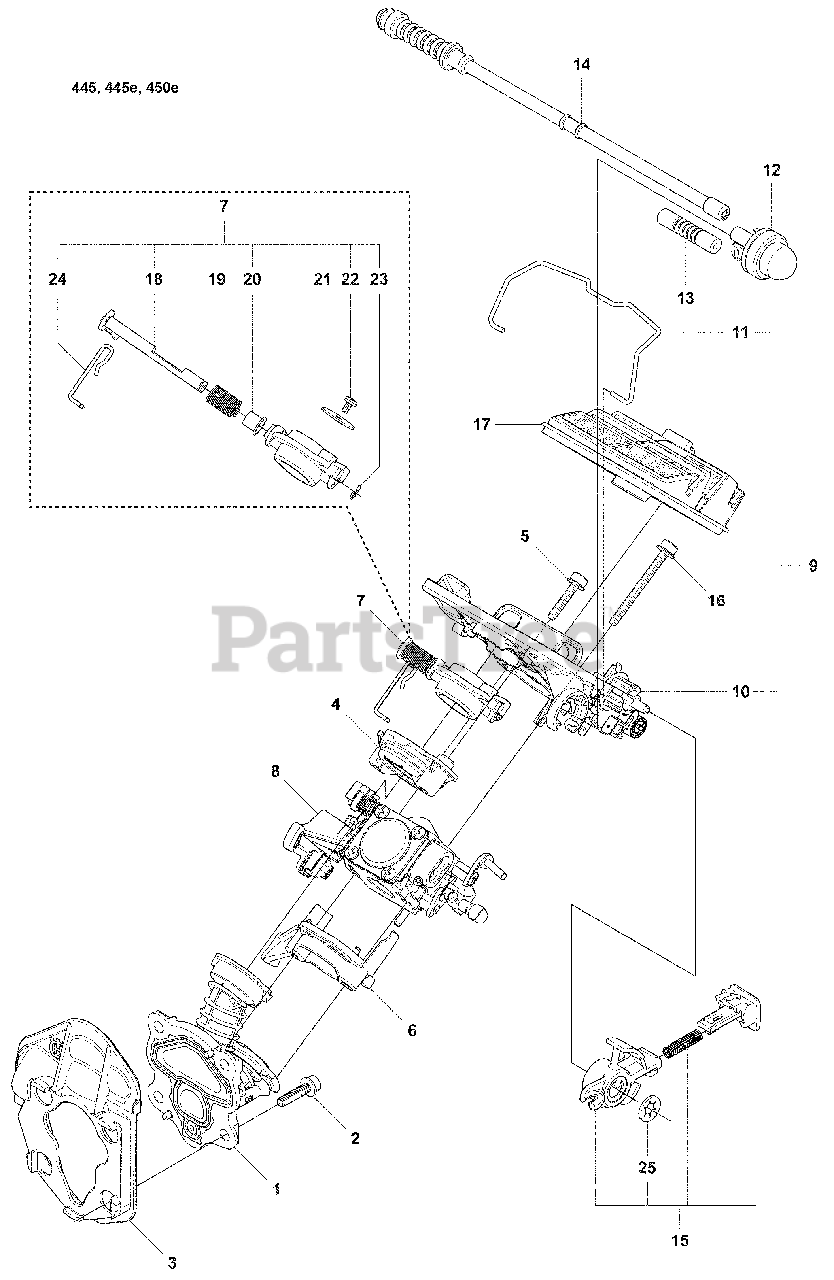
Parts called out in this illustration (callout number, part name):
1	Inlet Pipe Assembly
2	Screw, M5 X 16
3	Intermediate Wall
8	Carburetor Kit with Hose
9	Filter Holder Assembly
12	Air Purge Bulb
13	Suction Hose
14	Return Hose
17	Air Filter, Nylon 80
17	Air Filter, Nylon
17	Air Filter, Felt
18	Shaft Assembly
25	Lock Washer
